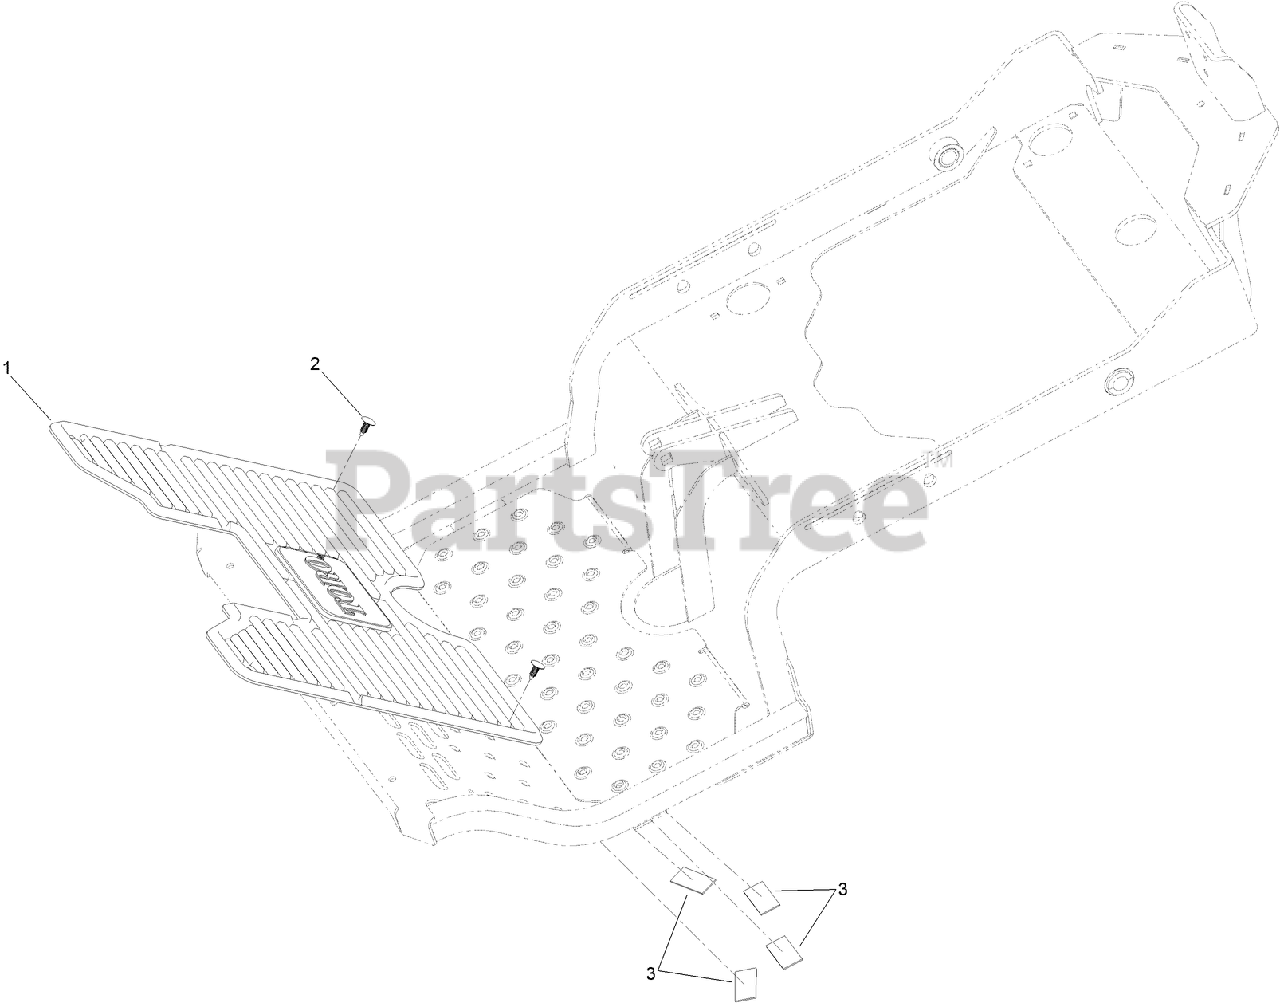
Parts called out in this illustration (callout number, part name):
1	MAT-FLOOR
2	PLUG-PLASTIC
3	PAD-RUBBER
